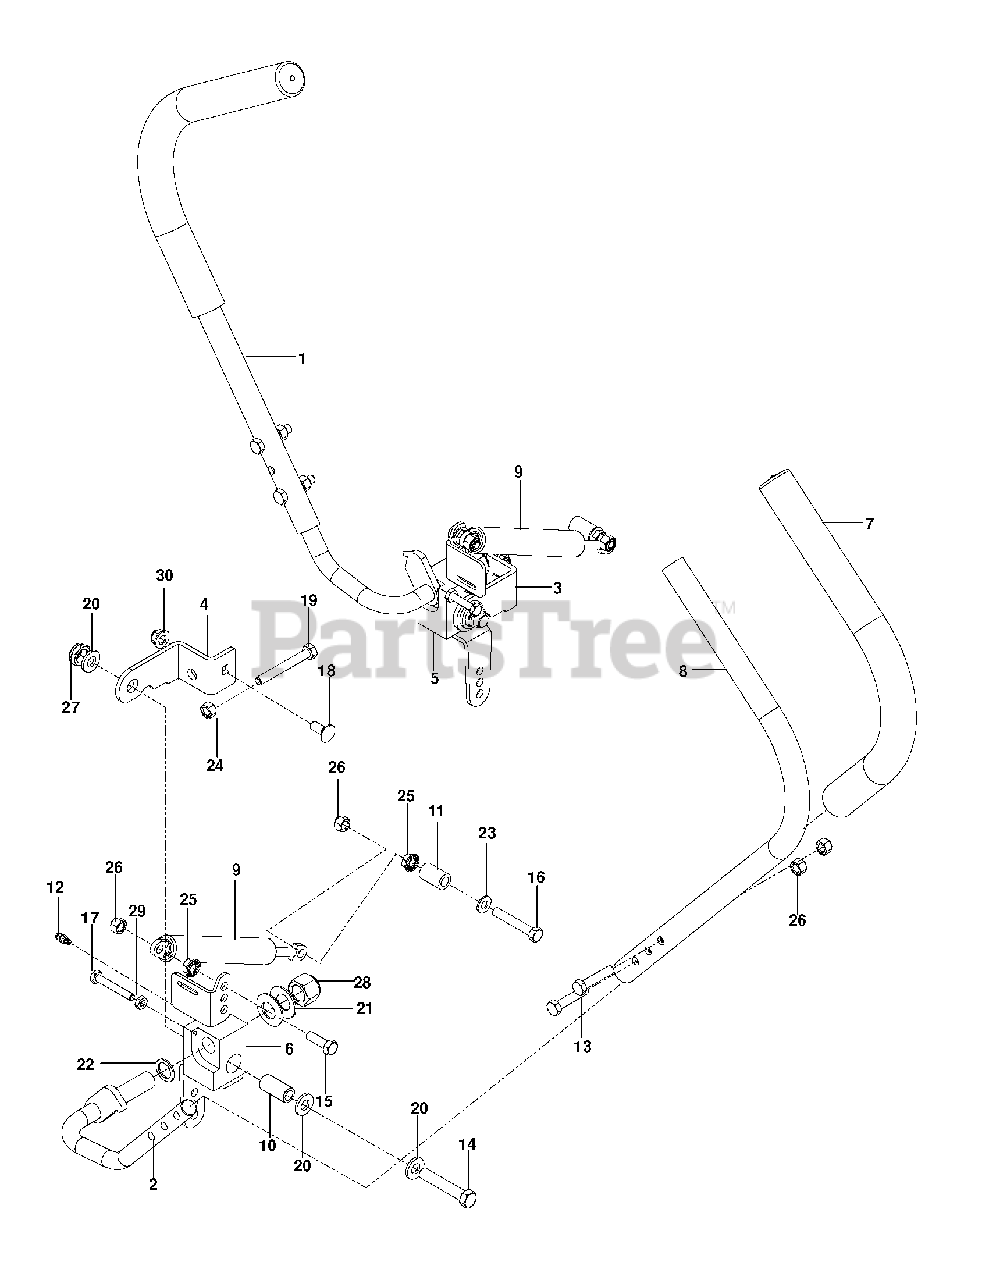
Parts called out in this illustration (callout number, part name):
1	PLATED LEVER RH
2	LEVER PLATED LH
3	FORWARD STOP RH
4	FORWARD STOP LH
5	PIVOT RH (PLATED)
6	PIVOT LH (PLATED)
8	LEVER UPPER
9	DAMPENER, DUAL ACTION
10	BUSHING
11	BUSHING
12	ZERK, 3/16, DRIVE IN
13	CAPSCREW 5/16 X 1/1/2 HEX HEAD
14	HCS 1/2C X 2 3/4
15	HCS 5/16C X 1
16	HCS 5/16-18X2
17	BOLT 1/4C X 1 3/4
18	BOLT 5/16C X 3/4" CARRIAGE
19	HCS 5/16-18 X 2 1/2 TPBLT
20	WASHER 1/2" FLAT
21	WASH 5/8 BEVELED DISC SPRING
22	WASHER-.626IDX.056TK
23	FLAT WASHER 5/16 SAE
24	NUT 5/16C HEX
25	NUT 5/16C WHIZ
26	NUT 5/16 NYLOC
27	NUT 1/2-13 HEX JM NYL
28	NUT 5/8-11 NYLOC
29	NUT 1/4-20 JAM
30	5/16-18 NYLOC FLANGE NUT
